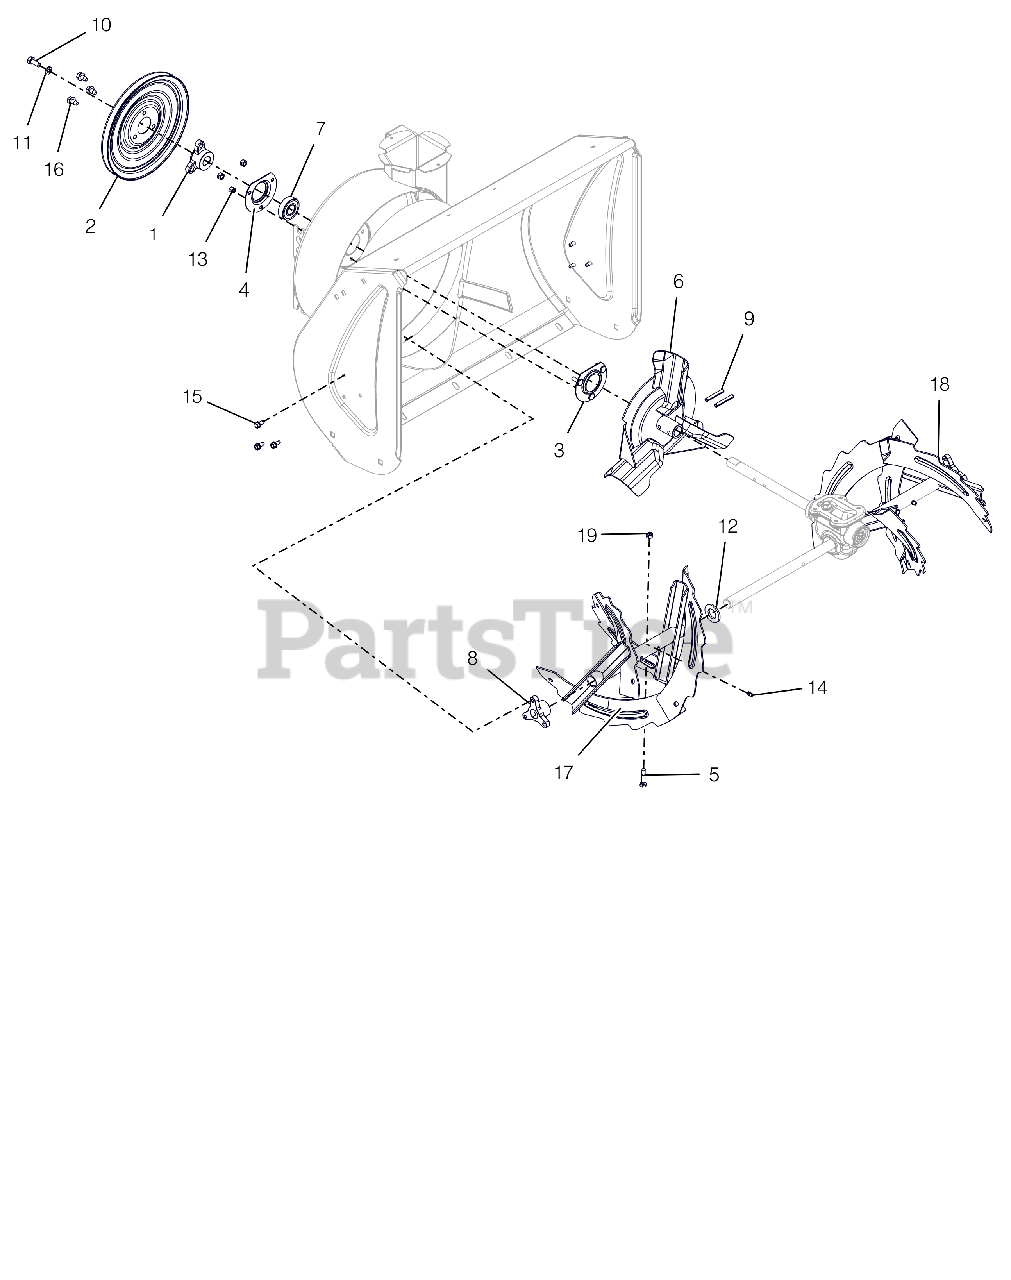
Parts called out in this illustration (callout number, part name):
1	PULLEY HUB, BOLT-ON D-BORE .75
2	PULLEY,SPIN FORM SINGLE GROOVE
3	BEARING FLANGE
4	BEARING FLANGE
5	SHEAR BOLT
6	IMPELLER, COMPACT 12" 3-BLADE
7	BRG-BALL .750X1.750X.50
8	BUSHING, RAKE SHAFT .75"
9	PIN-ROLL .250X1.75
10	BLT-HEX .31-24X.75 YWZC GR5
11	WSHR-LK .312X.097 HVY YWZC
12	@WSHR-FL-STL.812X1.50X.135YWZC
13	@NUT-LK-CTR .25-20 YWZC
14	ZERK,FITTING .25X.125 DRIVE IN
15	SCR-TAP .25-20X.50 HWH TR YWZ
16	@SCR-TAP .31-18X.50 HWH TR YWZ
17	RAKE, 24" RH, BLK SERR W/ZERK
18	RAKE, 24" LH, BLK SERR W/ZERK
19	@NUT-LK-CTR .25-20 YWZC
